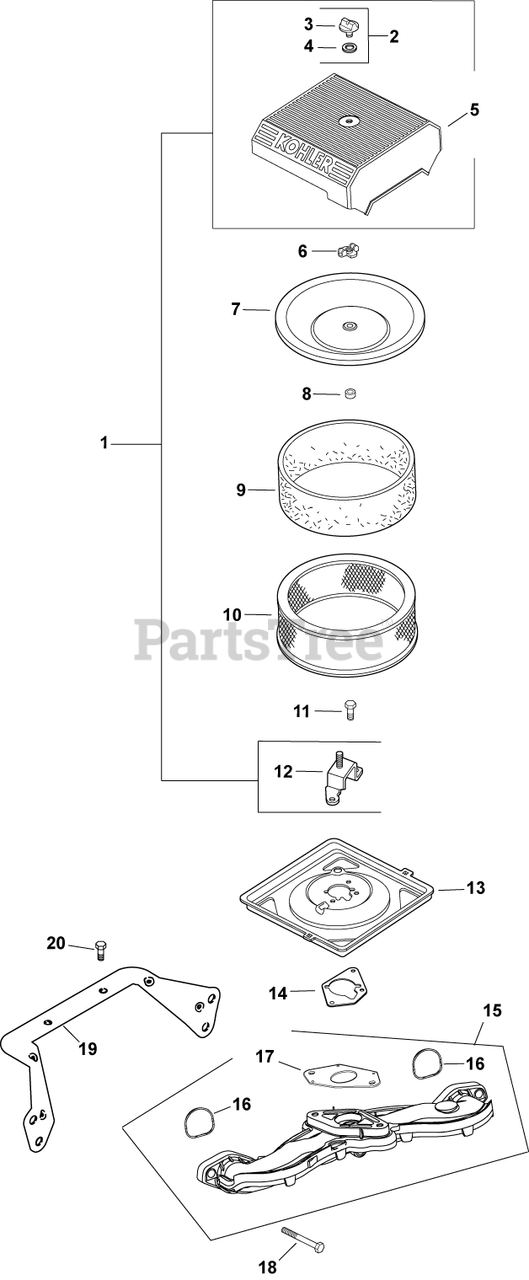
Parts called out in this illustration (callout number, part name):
1	KIT, AIR CLEANER COVER
2	KIT, KNOB W/SEAL
3	KNOB, COVER
5	COVER, AIR CLEANER
6	NUT, WING
7	COVER, INNER AIR CLEANER
8	SEAL, INNER AIR CLEANER
9	ELEMENT, PRECLEANER (LOW)
10	ELEMENT, AIR CLEANER - Also available Retail Packaged 47 883 03-S1 Air Filter Kit
11	SCREW, FLG THD FRM M5X.8X10
12	BRACKET,AIR CLEANERBASE-USE 24 126 206-S
13	BASE, AIR CLEANER-USE 24 094 84-S
14	GASKET, AIR CLEANER BASE
15	MANIFOLD, INTAKE - PLASTIC-USE 24 164 93
16	O-RING, INTAKE PORT
17	GASKET, CARBURETOR
18	SCREW, FLG M6X1.0X40
19	BRACKET, AIR CLEANER BASE
20	SCREW, FLG THD FRM M6X1.0X16
